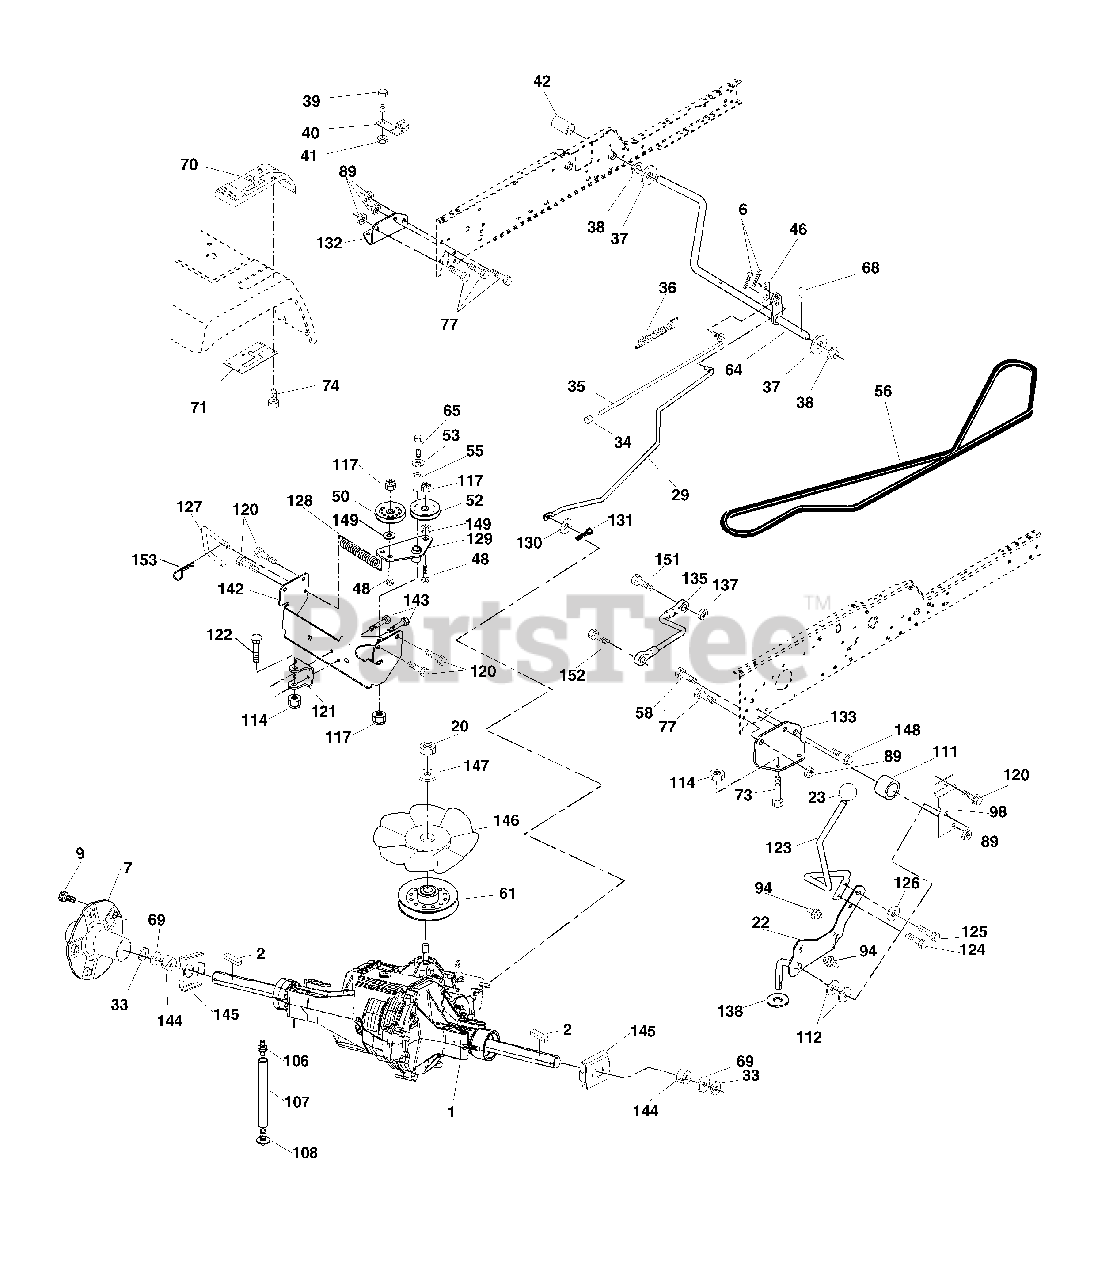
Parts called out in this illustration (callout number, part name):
2	Key Sq. 1/4 x 1/4 x 2
6	Pin, Cotter
7	Wheel, Hub Assembly
9	Bolt, Hub
20	Nut
22	Lever Asm Shift
23	Knob
29	Brake, Rod
33	Ring E
34	Cap, Parking Brake
35	Rod, Parking Brake
36	Spring, Drive Ground
37	Washer 25/32 x 1-1/4 x 16 Ga.
38	Nyliner
39	Screw, Fin. #10-24 x 1
40	Actuator, Interlock Switch
41	Nut Centerlock 10-24 Unc
42	Cover, Pedal
46	Retainer,Spring
48	Bolt Rdhd 3/8-16 x 1-3/4 Gr. 5
50	Pulley, Idler, Flat
52	Pulley, Idler, Grooved
53	Washer,Hardened
55	Bearing, Idler
56	V-Belt
58	Bolt Fin Hex 7/16-14 x 1-1/2
61	Pulley, Transaxle
64	Shaft, Brake Pedal
65	Bolt, Shoulder
68	Pin, Roll
71	Plate Console Shift
73	Bolt Hex Flghd 5/16-18 x 3 Gr5
74	Screw Hex Wsh. Hi-Lo 1/4-1/2
77	Bolt Fin Hex 7/16-14 x 1
89	Nut Crownlock 7/16-14 Unc
94	Fastener Christmas Tree
98	Bracket Shift
106	O-Ring Asm Hydro Gear
107	Line Fuel Hydro 15" VGT
108	Cap Asm Vent Hydro Gear
111	Spacer Shift Lever VGTH
112	Washer Nylon High Temp
114	Nut Lock Hex W/Ins 5/16-18 Unc
117	Nut, Lock Flg. 3/8-16
120	Screw 3/8-16 x .75
121	Bracket Strap Torque
122	Bolt 5/16-18 x 2.50
123	Rod Shift
124	Bolt Shoulder 5/16-18 x .561
125	Screw 5/16-18 x 5/8
126	Washer SRRTD 5/16 ID x 1.0 x .125
127	Link Control Clutch
128	Spring Drive GRND
129	Bracket Asm Idler Tensioning
130	Washer 13/32 x 5/8 x 16 Ga.
131	Pin Cotter 3/32 x 1/2
132	Bracket Mtg Hydro 3500 LH VGT
133	Bracket Mtg Hydro 3500 RH VGT
134	Arm Shift Hydro 3500
135	Link Asm Control Hydro 3500
136	Nut Lock 5/16-18 NC Thd.
137	Bolt Fin Hex 5/16-18 Unc x 1.00
138	Washer Thrust 5/8 x 1.10 x 1/32
139	Bolt 1/4-28 Unf Gr8 w/Patch
140	Washer Lock Hvy. Helical 1/4
141	Washer 9/32 x 3/4 x 10 Ga.
142	Strap Torque HG-3500
143	Screw 5/16-18 x 3/4
144	Washer Spacer Axle HG-3000
145	Washer Axle Flange HG-3000
146	Fan 7" Hydro
147	Washer
148	Screw 3/8-16 x 1.0
149	Washer 13/32 x 7/8 x 10 Ga.
153	Spring,Retainer
